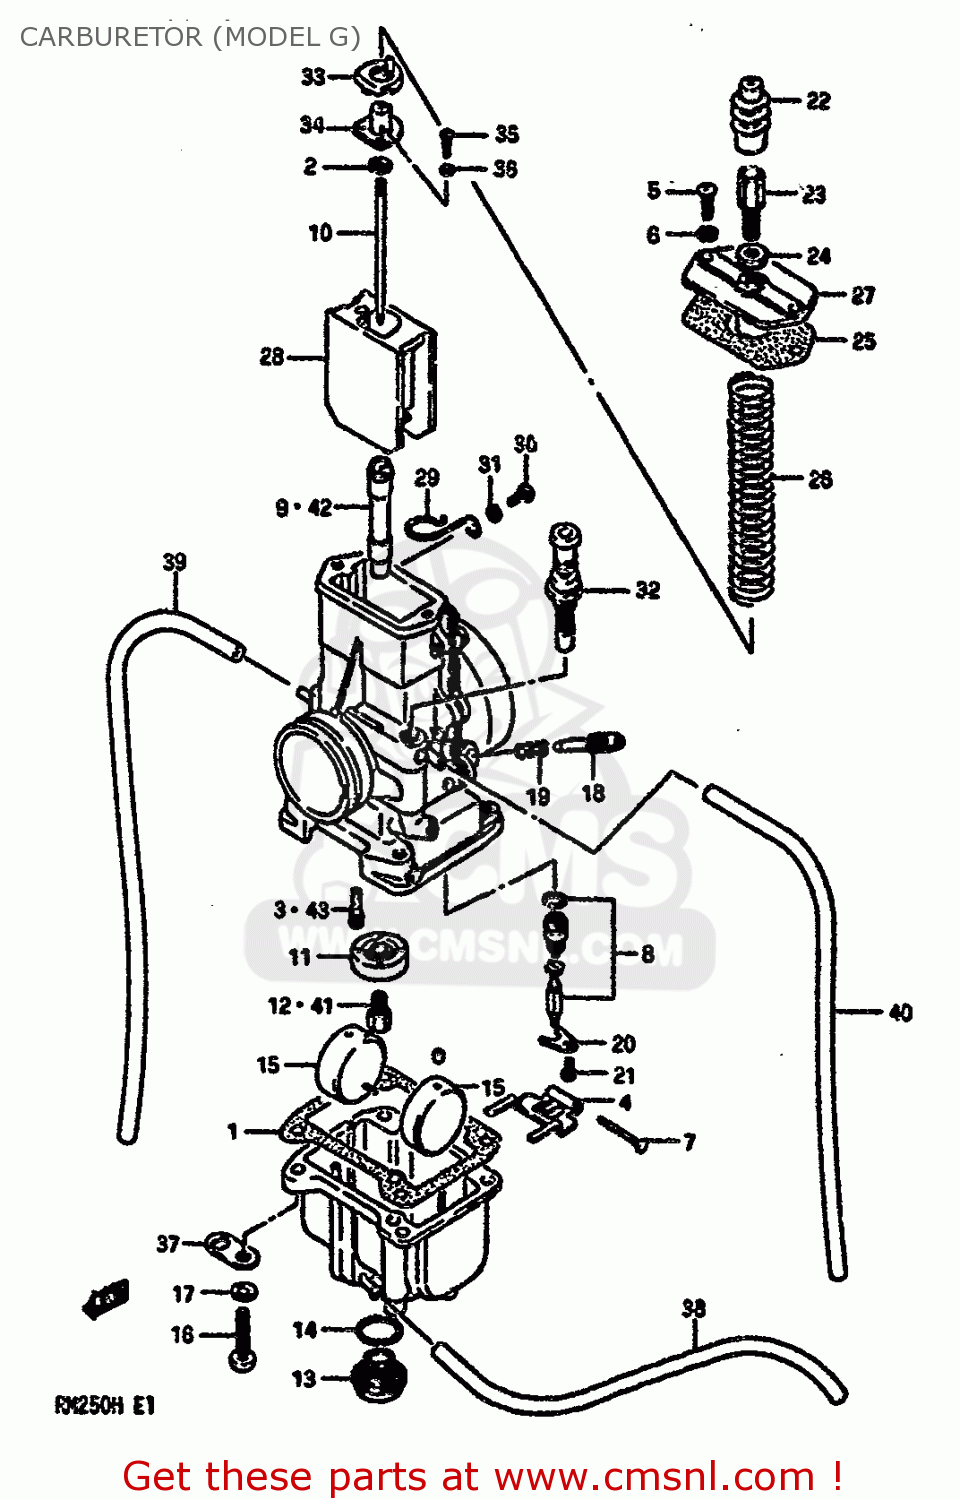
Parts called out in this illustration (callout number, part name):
1	GASKET,FLOAT CAHMBER (NAS)
2	CLIP
3	JET,PILOT(50)
4	ARM,FLOAT
5	SCREW
6	LOCK WASHER
7	PIN,FLOAT
8	VALVE ASSEMBLY,NEEDLE
9	JET,NEEDLE(R-0)
10	NEEDLE JET
11	RING,MAIN JET FIXING
12	JET,MAIN(300)
13	SCREW,GUIDE
14	O RING,DRAIN PLUG
15	FLOAT
16	SCREW
17	LOCK WASHER
18	SCREW,PILOT AIR
19	SPRING
20	PLATE
21	SCREW
22	CAP,CABLE ADJUSTER
23	ADJUSTER,CABLE
24	NUT
25	GASKET,MIXING CHAMBER (NAS)
26	SPRING,THROTTLE VALVE
27	CAP,CARBURETOR,TOP
28	VALVE,THROTTLE,CA (3.0)
29	CLIP
30	SCREW
31	LOCK WASHER
32	PLUNGER ASSEMBLY
33	SEAT,RETURN SPRING
34	PLATE,NEEDLE JET
35	SCREW
36	LOCK WASHER
37	PLATE
38	HOSE
39	HOSE
40	HOSE
41	JET
42	JET,NEEDLE
43	JET,PILOT
